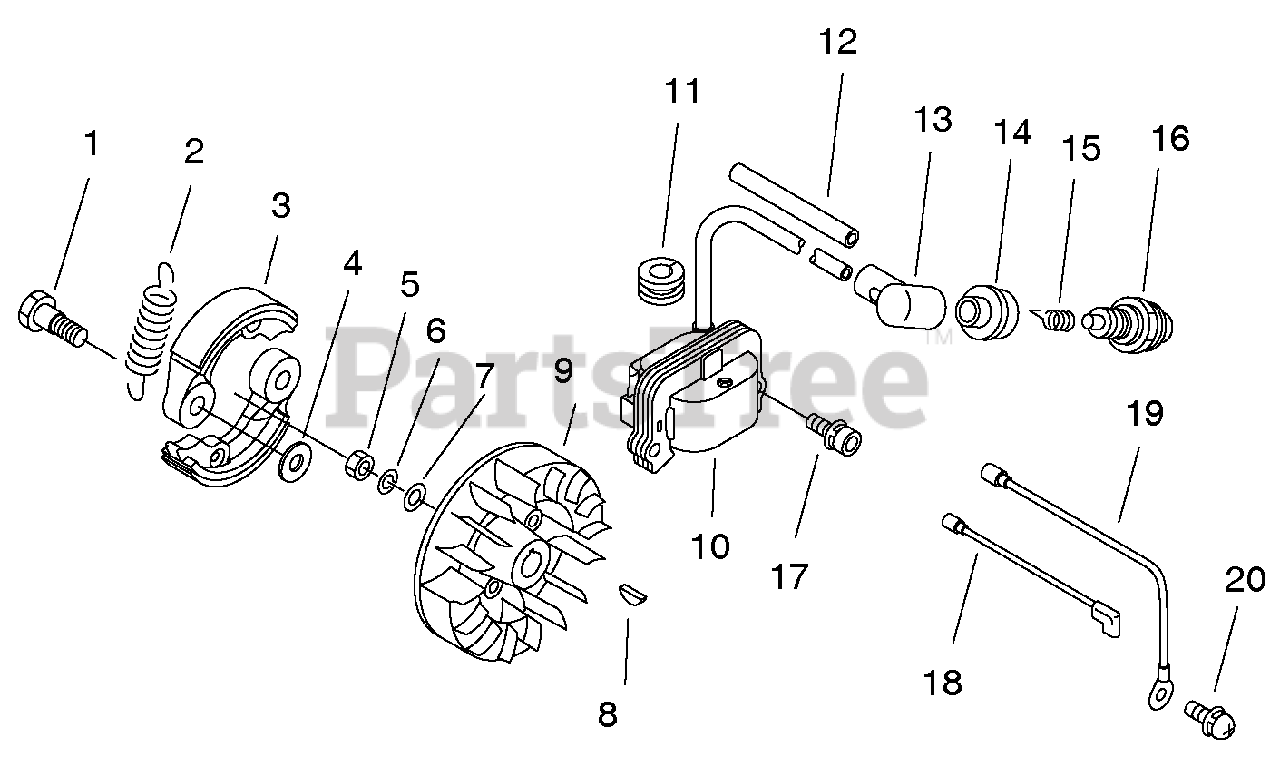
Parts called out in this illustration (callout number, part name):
1	BOLT, CLUTCH
2	SPRING, CLUTCH
3	SHOE, CLUTCH
4	WASHER - 6
6	LOCKWASHER - 8
7	WASHER - 8
9	FLYWHEEL
10	COIL, IGNITION
11	GROMMET
13	CAP, SPARK PLUG
14	COVER, PLUG CAP
15	TERMINAL, SPARK PLUG CAP
16	SPARK PLUG -- BPMR-7A
17	SCREW - 5X20
18	LEAD - IGNITION
19	LEAD - GROUND
20	SCREW - 5X10
